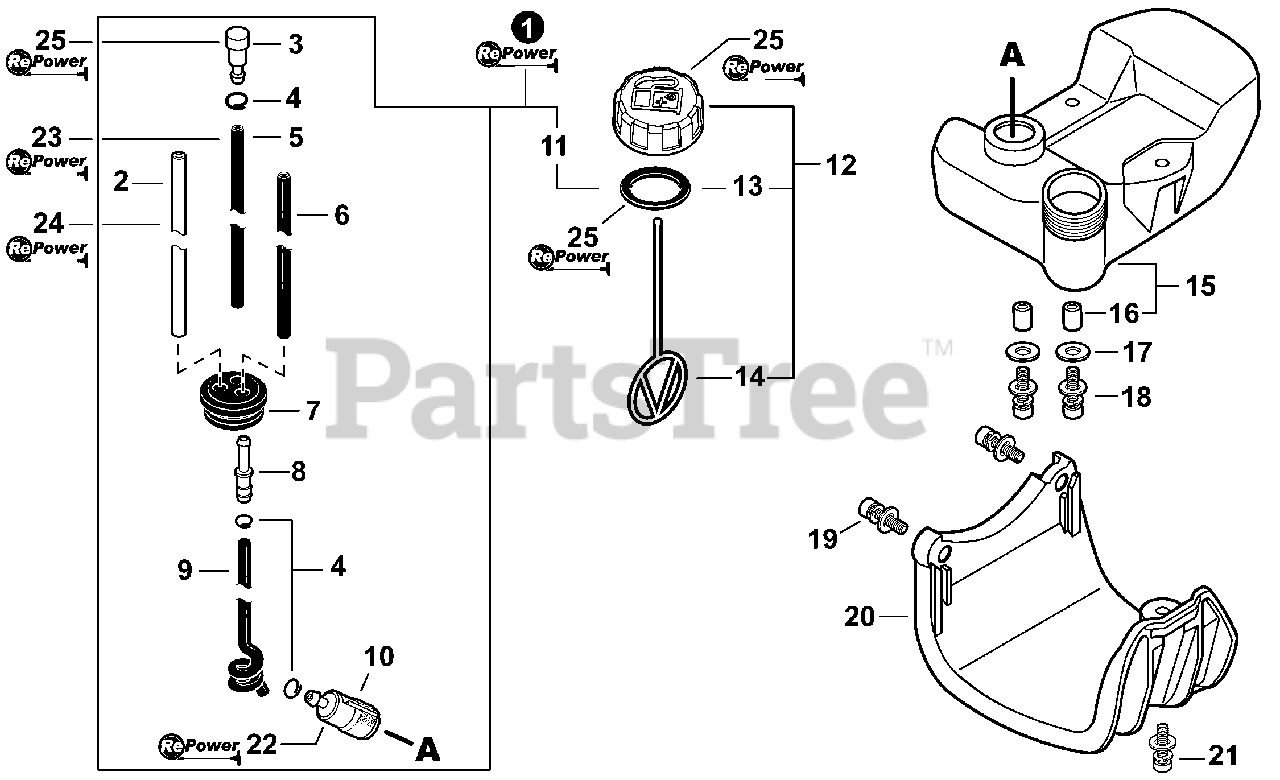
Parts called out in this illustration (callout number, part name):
1	FUEL SYSTEM KIT - REPOWER
2	PIPE, FUEL 3×6×80 CLEAR
3	VENT ASSY
4	CLIP Ø6.5MM
5	PIPE, FUEL 3×6×115 BLACK
6	PIPE, FUEL 3×5×74 BLACK
7	GROMMET, FUEL
8	CONNECTOR, PIPE Ø5ר3.5
9	PIPE, FUEL 3×6×105
10	FILTER, FUEL
11	GASKET, FUEL CAP
12	CAP ASSY, FUEL
13	GASKET, FUEL CAP
14	CONNECTOR, CAP L= 100mm
15	TANK, FUEL
16	SPACER 6.2×7.8×6
17	WASHER 5.5×12×0.8
18	BOLT 5×16
19	BOLT 5×22
20	GUARD, FUEL TANK
21	SCREW 5×20
22	TUNE-UP KIT - REPOWER
23	PIPE, BULK - 3×6mm BLACK
24	PIPE, BULK - 3×6mm CLEAR
25	CAP/VENT KIT - REPOWER
